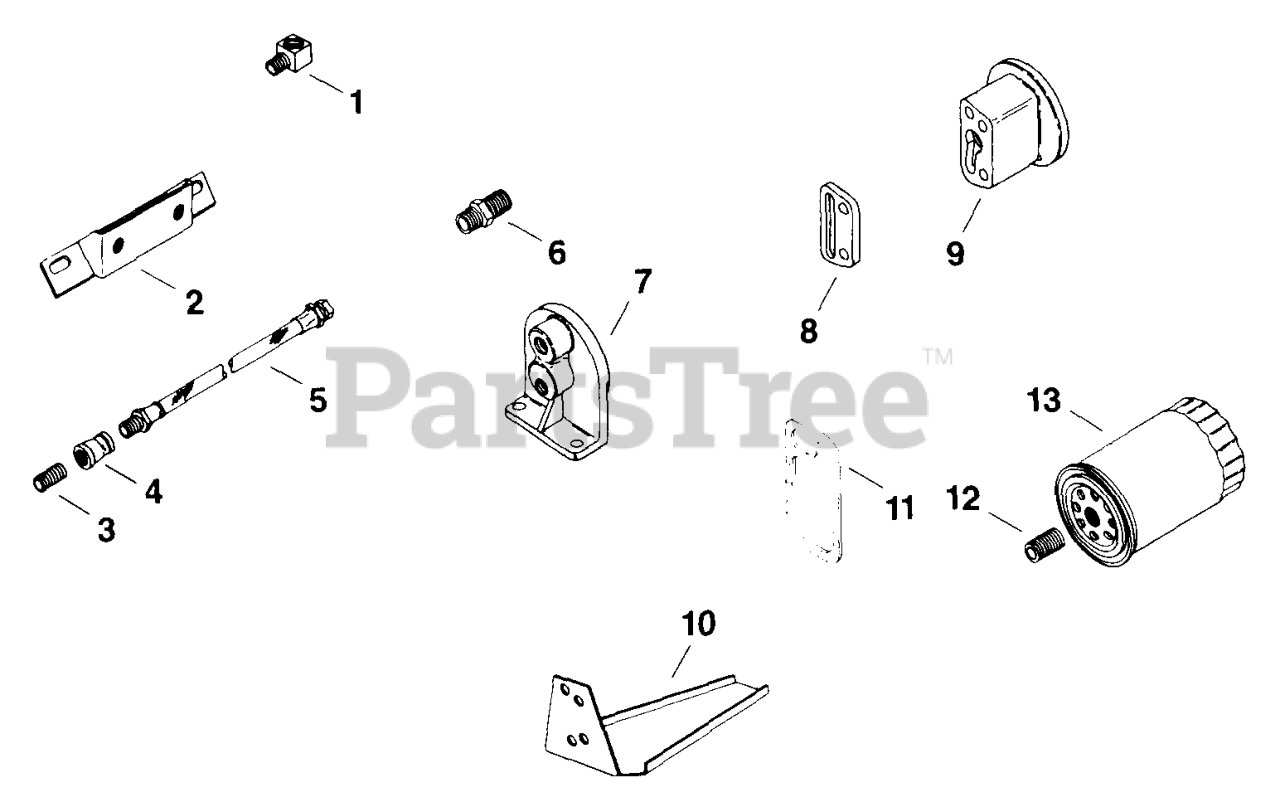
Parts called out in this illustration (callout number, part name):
9	ADAPTER - USE 48 029 02
11	GASKET - USE 48 041 03
13	FILTER, OIL
